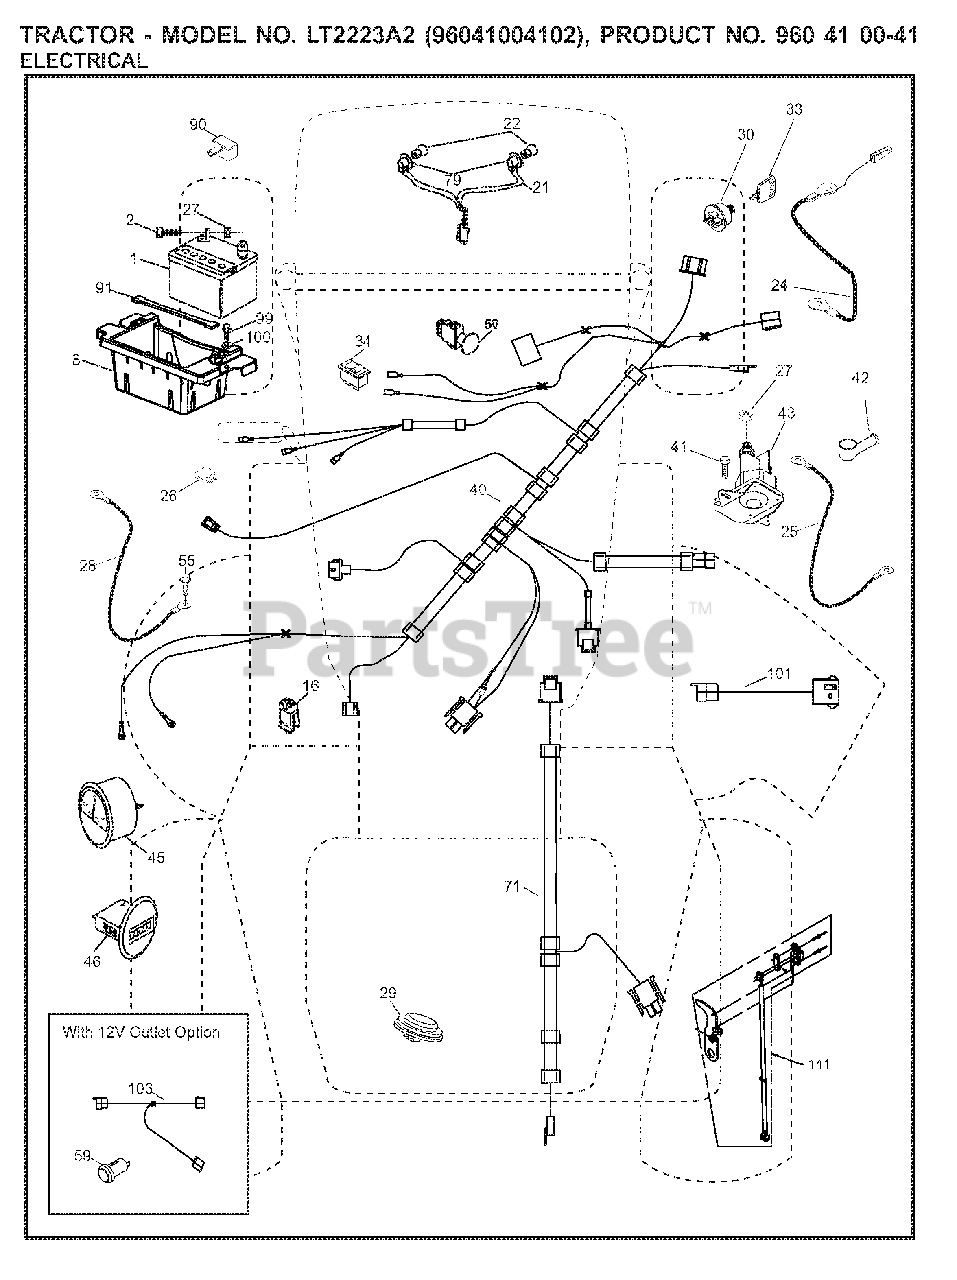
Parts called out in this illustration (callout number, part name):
1	BATTERY 12V .35 AMP
8	BOX.BATTERY.MOUNT.FRONT.LT
16	SWITCH INTERLOOK PUSH-IN
21	HARNESS.W/LIGHT SOCKET
22	LIGHTBULB
24	CABLE.BATT.POS.WIRE.TG.DA SOL
25	CABLE.START.RED.17.5".
26	FUSE 20AMP
27	NUT
28	CABLE GROUND 6 GA 21" 90T BLK
29	SWITCH.SEAT.DELTA.OPC.
30	SWITCH.IGN.DELTA.W.LGH.ROS
33	KEY.CHAIN.BLISTER.PACK.GEN.INT
34	SWITCH LT
40	HARNESS IGN. DASH
41	SCREW
42	TERMINAL COVER
43	SOLENOID.W/BRASS.PLUNG
46	HOURMETER SNAP-IN
50	PTO SWITCH
55	SCREW 5/16"
71	HARNESS-CHASSIS SUB
79	BULB HOLDER ASM.
90	COVER.TERMINAL.BATTERY
91	STRAP, BATTERY MOUNT
99	SCREW HEXWSHR 1/4-20X3/4
101	PIGTAIL.MATNLK.NEW.HAR
